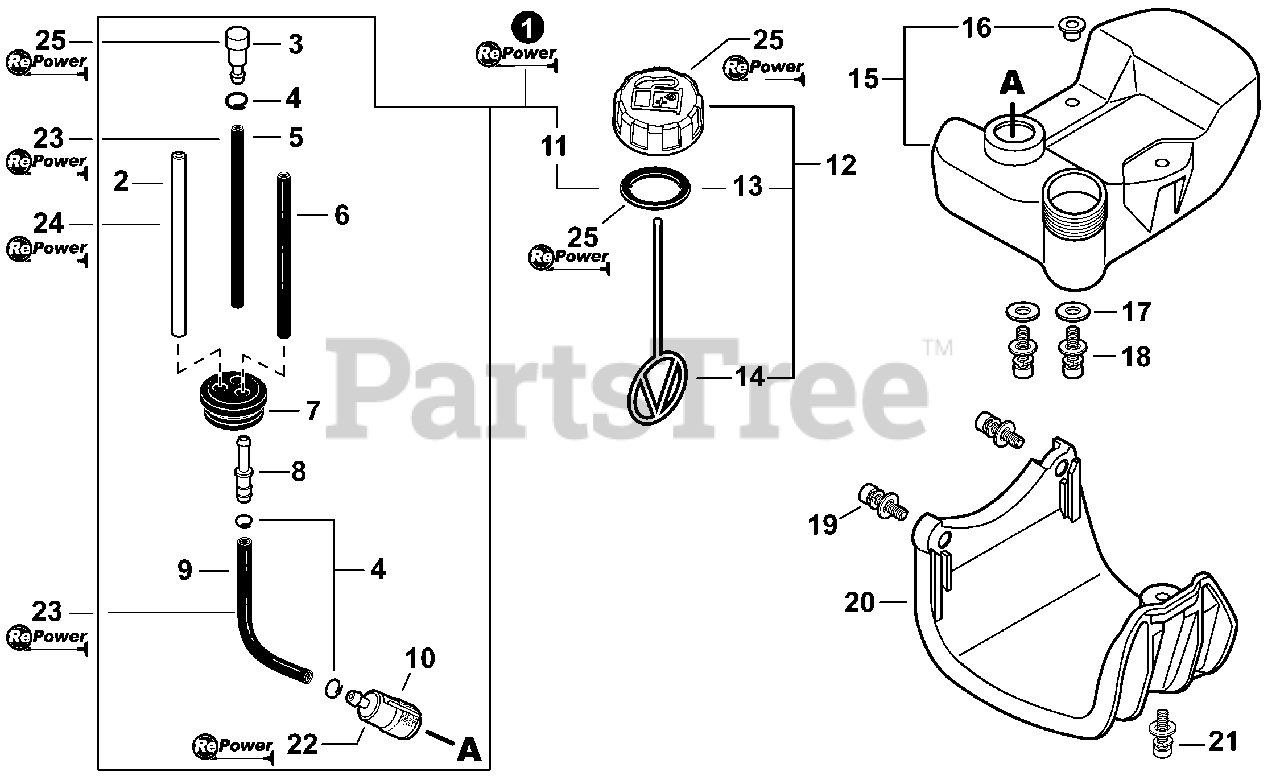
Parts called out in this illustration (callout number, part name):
1	FUEL SYSTEM KIT - REPOWER
2	PIPE, FUEL 3×6×80 CLEAR
3	VENT ASSY
4	CLIP Ø6.5MM
5	PIPE, FUEL 3×6×115 BLACK
6	PIPE, FUEL 3×5×74 BLACK
7	GROMMET, FUEL
8	CONNECTOR, PIPE Ø5ר3.5
9	PIPE, FUEL 3×6×100
10	FILTER, FUEL
11	GASKET, FUEL CAP
12	CAP ASSY, FUEL
13	GASKET, FUEL CAP
14	CONNECTOR, CAP L= 100mm
15	TANK, FUEL
16	COLLAR 5
17	WASHER 5.5×12×0.8
18	BOLT 5×18
19	BOLT 5×22
20	GUARD, FUEL TANK
21	SCREW 5×20
22	TUNE-UP KIT - REPOWER
23	PIPE, BULK - 3×6mm BLACK
24	PIPE, BULK - 3×6mm CLEAR
25	CAP/VENT KIT - REPOWER
